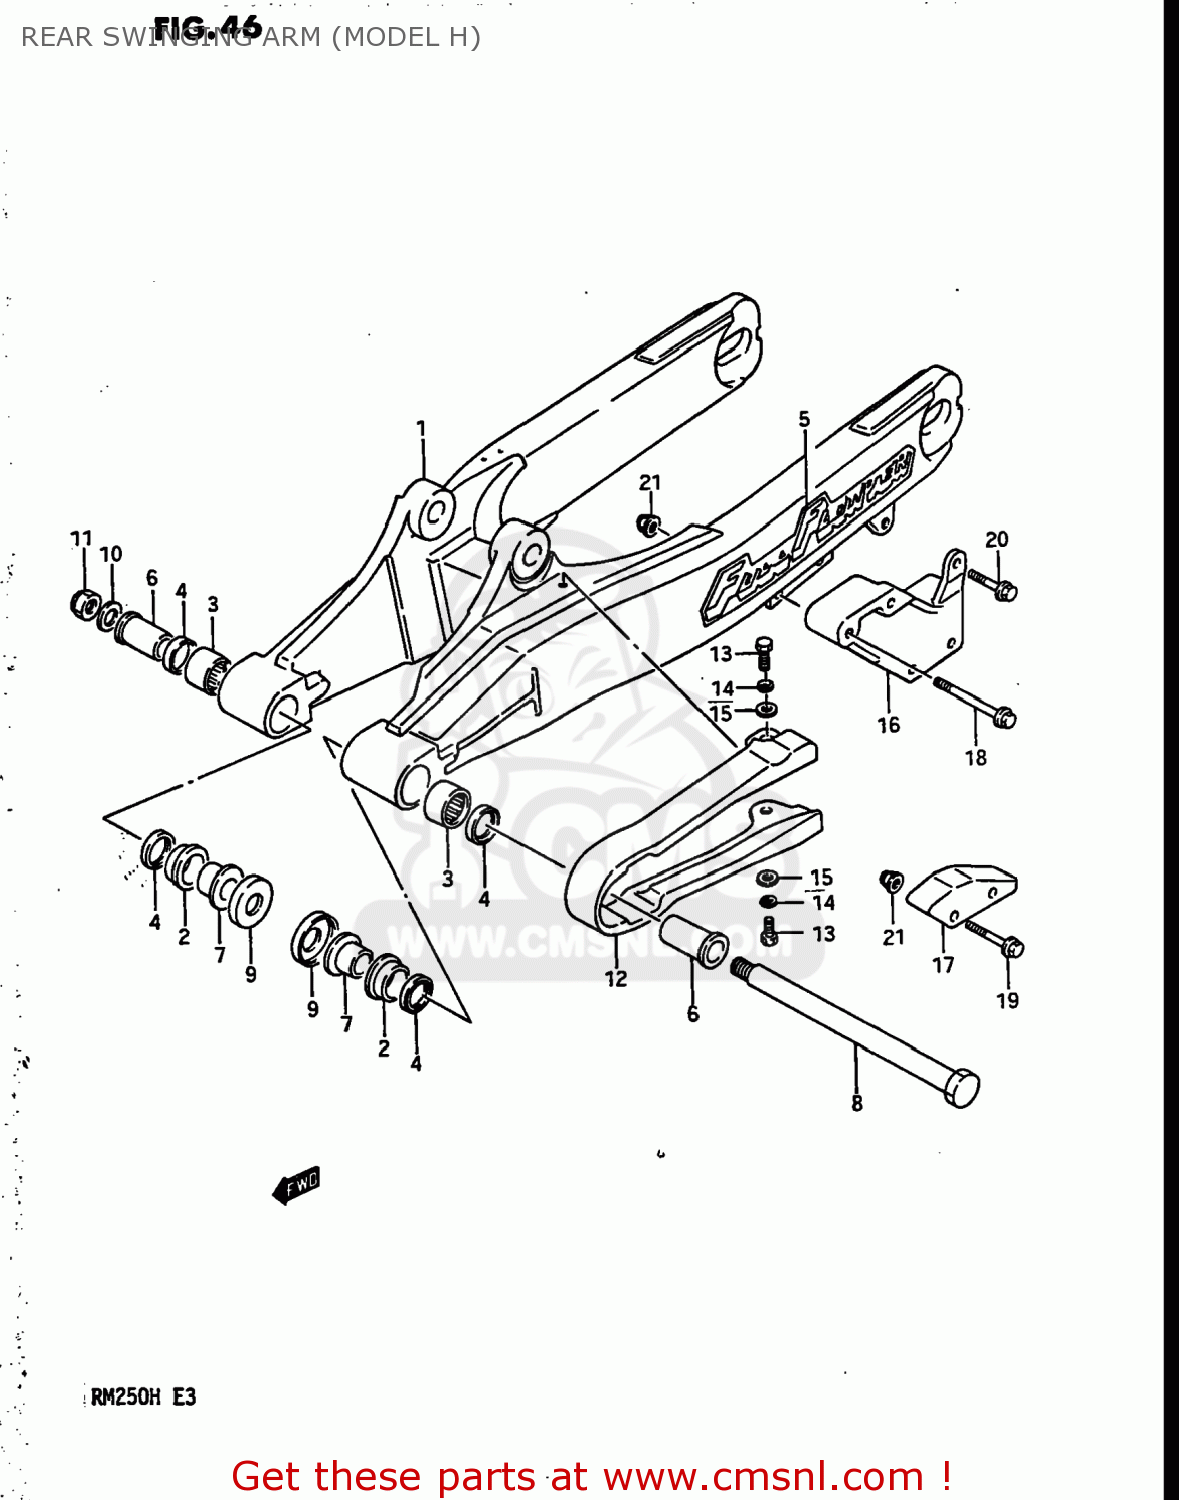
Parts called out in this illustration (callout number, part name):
1	SWING ARM ASSEMBLY,REAR
2	BUSHING,REAR SWING ARM PIVOT
3	BEARING(20X27X30)
4	OIL SEAL
5	LABEL (FRONT CARRIER WARNING)
6	SPACER,RR SWINGING ARM PIVOT
7	SPACER,RR SWGARM PIVOT INNER
8	SHAFT,RR SWINGINGARM PIVOT
9	COVER,RR SWGARM DUST SEAL
10	WASHER(14.5X29X2.3)
11	NUT
12	BUFFER,CHAIN TOUCH DEFLECTOR
13	BOLT
14	WASHER,LOCK
15	WASHER(6.5X16X1.2)
16	GUIDE,CHAIN
17	DEFENSE,CHAIN GUIDE
18	BOLT
19	BOLT,UNDER
20	BOLT,REAR
21	NUT
